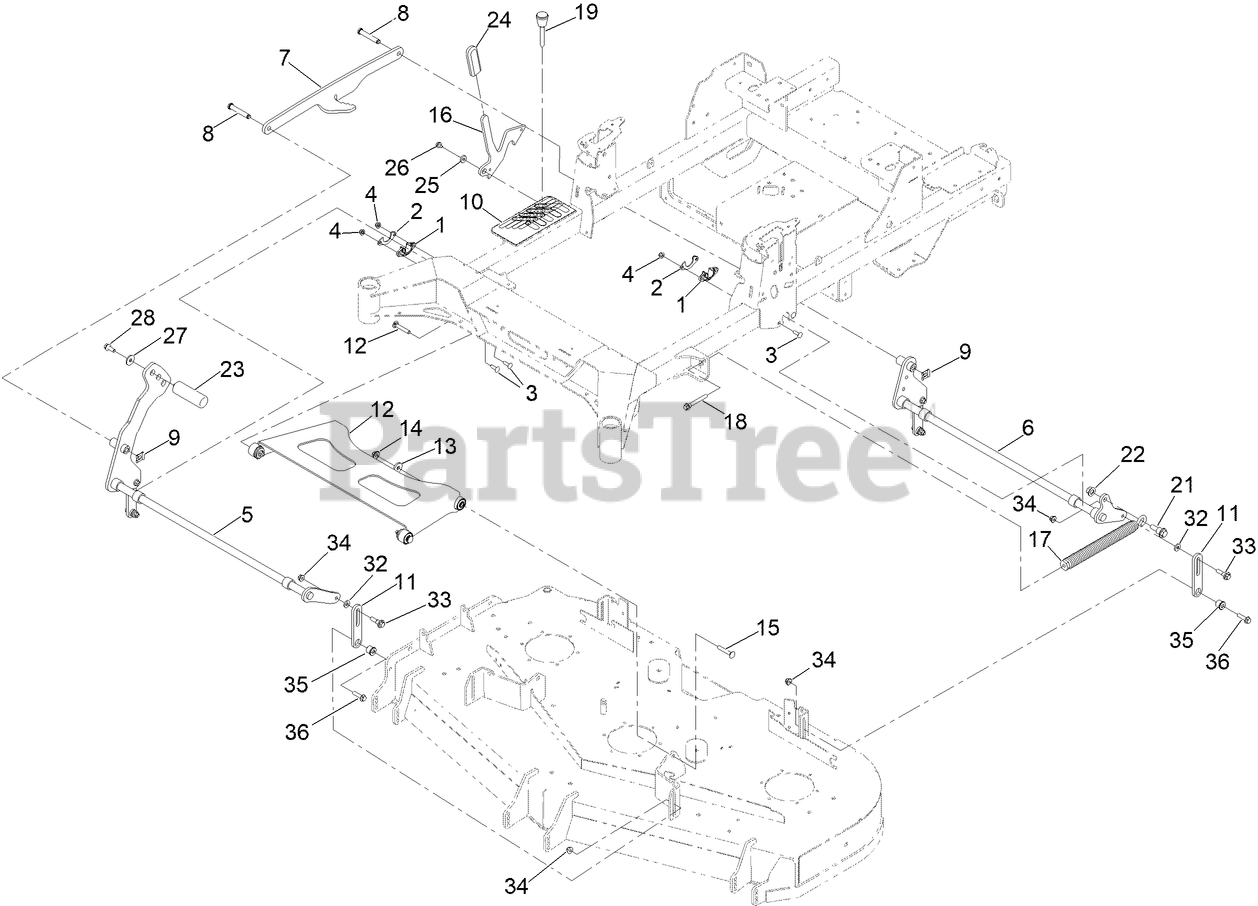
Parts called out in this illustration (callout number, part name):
1	BEARING-FLANGE
2	GUSSET-LIFT, DECK
3	SCREW-CARR
4	NUT-HF, NI
5	SHAFT-LIFT, DECK
6	DECK LIFT SHAFT ASM [BLACK]
7	LINK-LIFT
8	PIN-CLEVIS
9	CLIP-PIN
10	DECAL-HOC
11	LINK-LIFT, DECK
12	ASM-DECK STRUT W/ BUSHINGS
13	WASHER
14	NUT-FLANGE, NI
15	SCREW-CARR
16	PLATE-TRANSPORT LOCK
17	SPRING-EXTENSION
18	BOLT-SHOULDER
19	PIN-HOC
21	SCREW-SHOULDER, HHF
22	NUT-LOCK
23	PEDAL-FOOT LIFT
24	GRIP-LEVER
25	SPACER
26	SCREW
27	WASHER
28	SCREW-HHF
32	SPACER
33	BOLT-SHOULDER
34	NUT-HF, NI
35	BUSHING-DECK LIFT
36	SCREW-HHF
